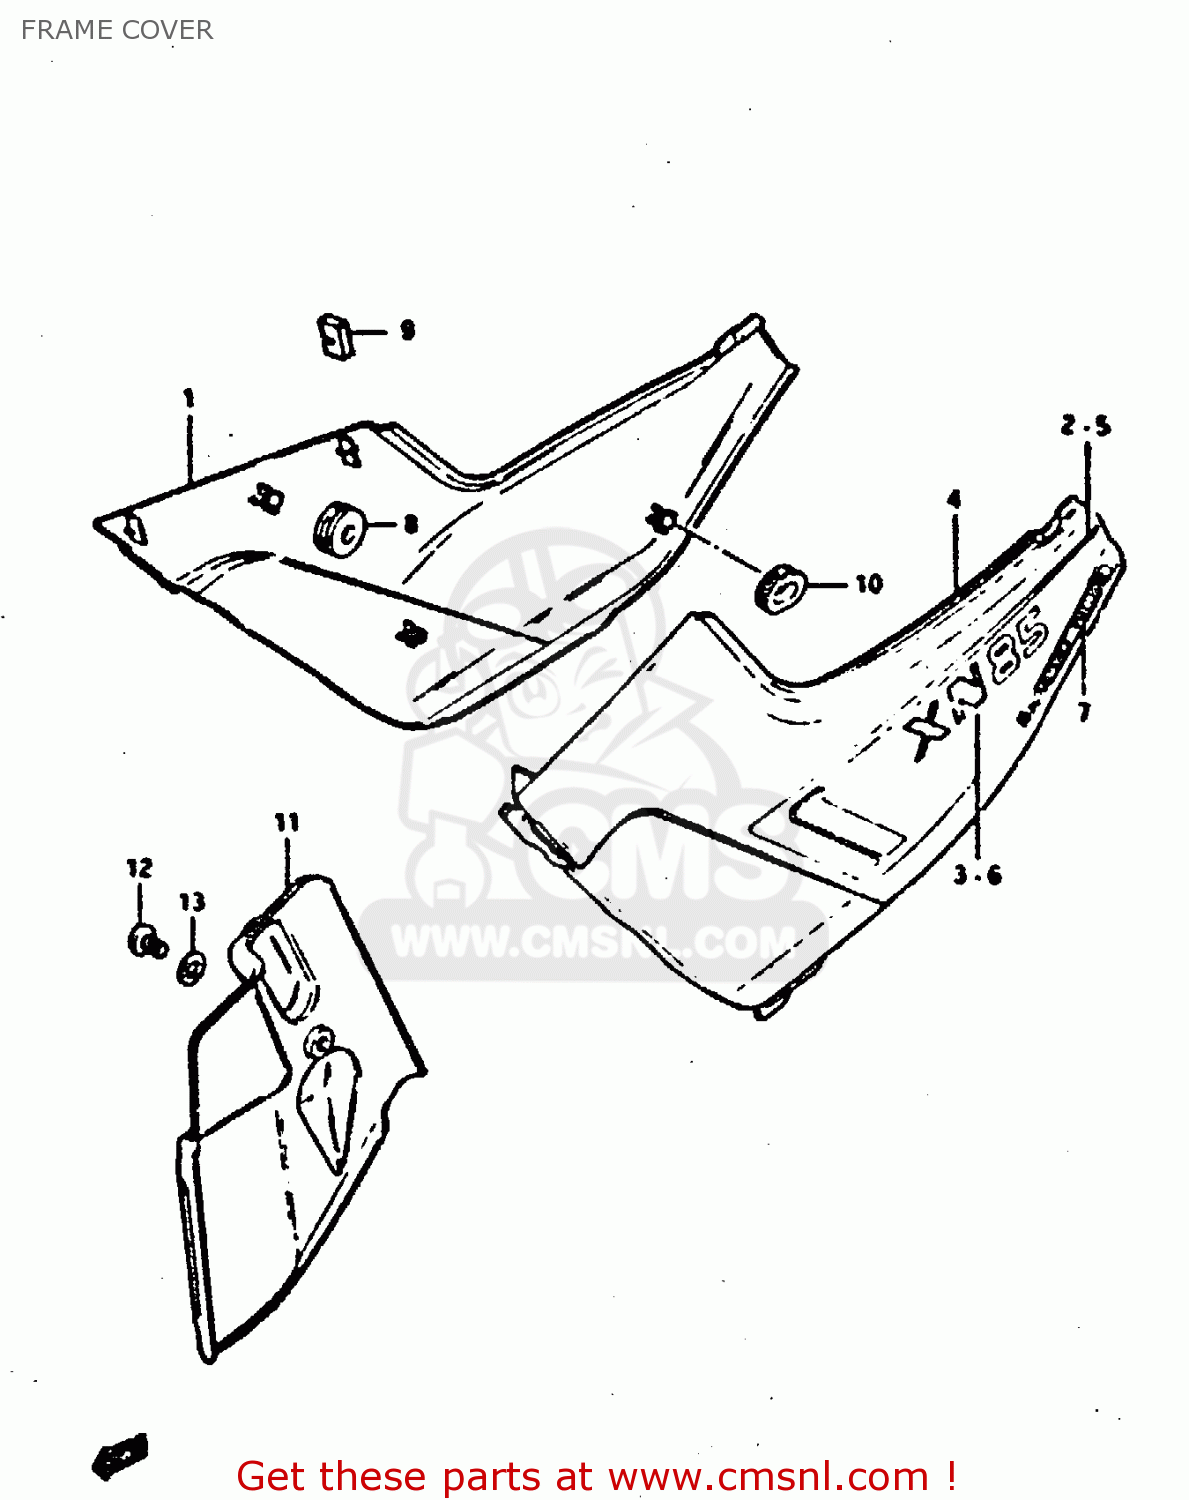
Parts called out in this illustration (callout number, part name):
1	COVER,FRAME,RIGHT
2	TAPE SET,FRAME COVER
3	EMBLEM (XN85)
4	COVER,FRAME,LEFT
5	TAPE SET,FRAME COVER
6	EMBLEM (XN85)
7	EMBLEM,ADJUSTER
8	CUSHION
9	CUSHION
10	CUSHION
11	COVER,FUEL PUMP
12	SCREW 6X12
13	WASHER
